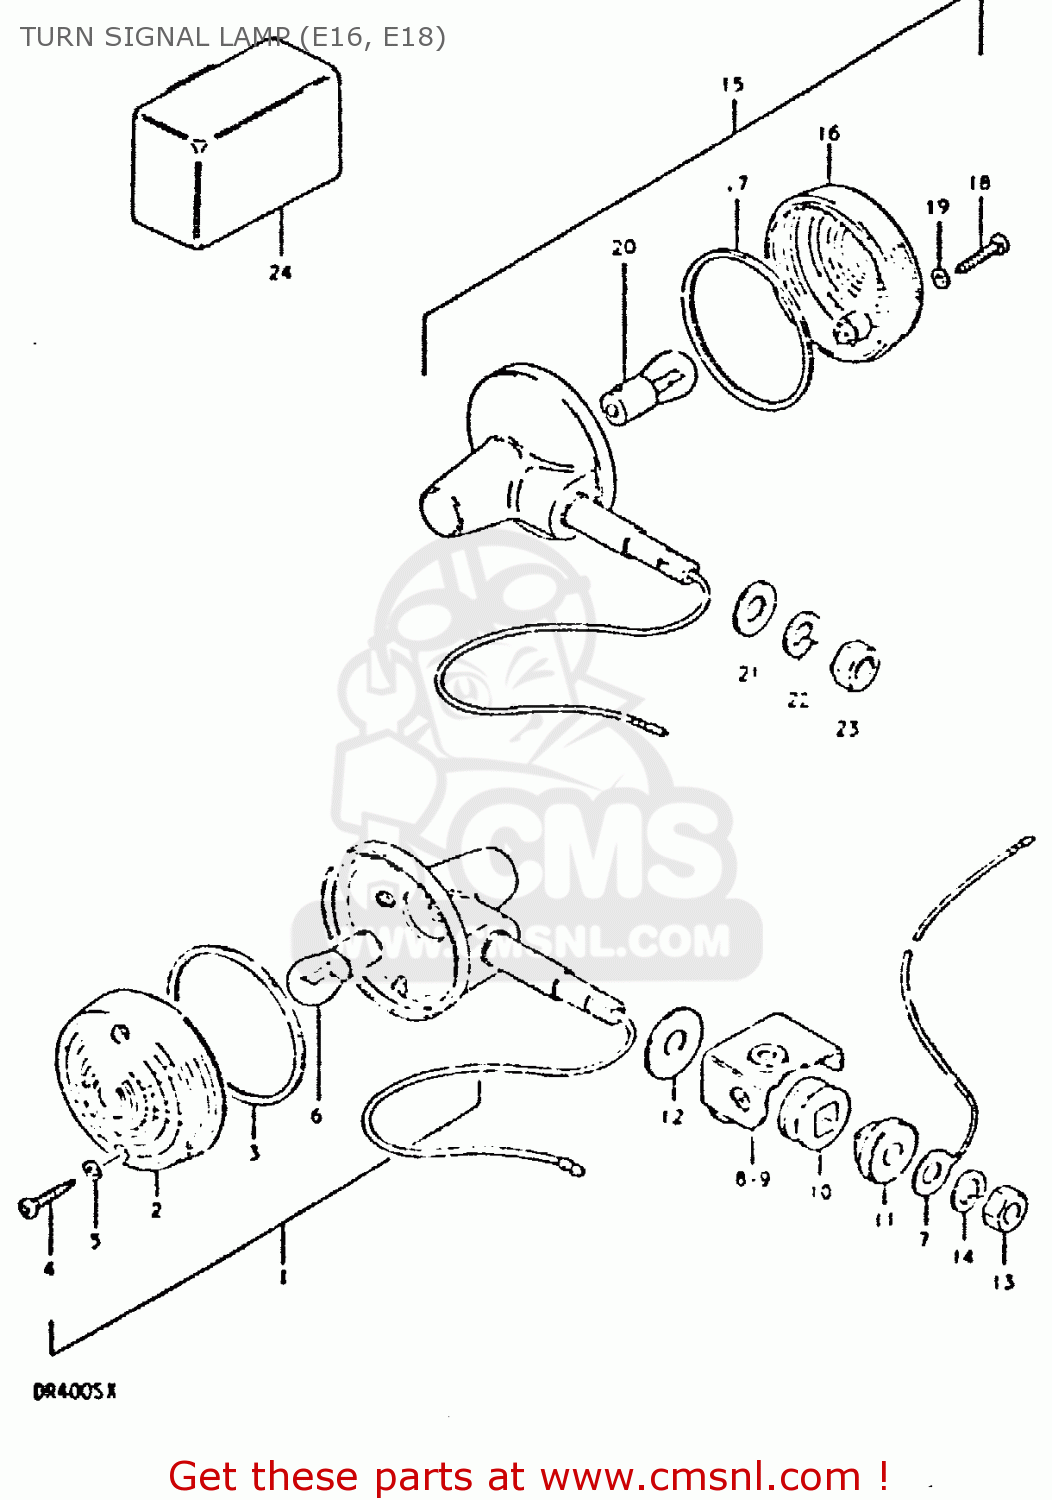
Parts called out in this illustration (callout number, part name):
1	LAMP, FRONT TURN SIGANL
2	LENS
3	GASKET (NAS)
4	SCREW
5	GASKET (NAS)
6	BULB (6V,21W)
7	LEAD WIRE,EARTH
8	BRACKET, FRONT RH
9	BRACKET, FRONT LH
10	CUSHION
11	SPACER,TURN SIGNAL LAMP
12	WASHER (10.5X30X2.3)
13	NUT
14	LOCK WASHER
15	LAMP, REAR TURN SIGNAL
16	LENS
17	GASKET (NAS)
18	SCREW
19	GASKET (NAS)
20	BULB (6V,21W)
21	WASHER
22	LOCK WASHER
23	NUT
24	RELAY, TURN SIGNAL
